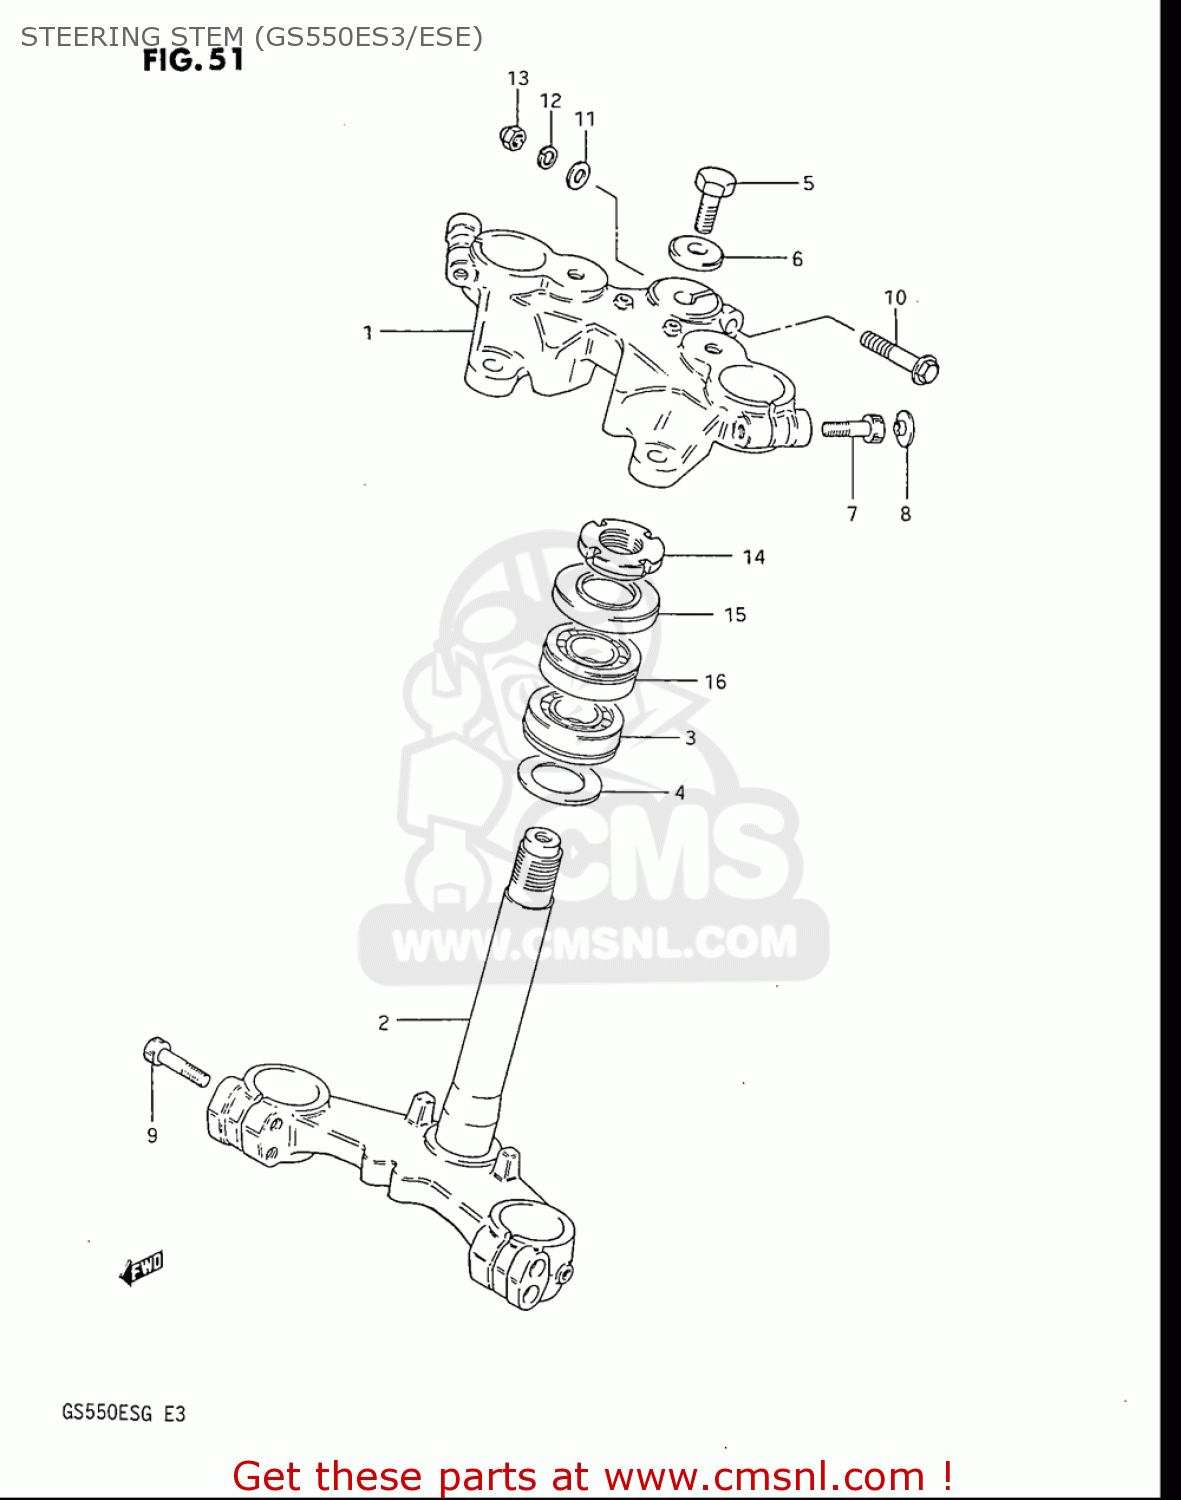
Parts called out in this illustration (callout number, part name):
3	BEARING(30X55X17)
4	SHIM(30X40X1.5)
5	BOLT,STEERING STEM HEAD
6	WASHER,STEERING STEM
7	BOLT,FORK INNER TUBE FITTING
8	CAP(OD:20)
9	BOLT
10	BOLT
11	WASHER
12	WASHER,LOCK
13	NUT
14	NUT,STEERING STEM
15	DUST SEAL,STEERING UPR
16	BEARING(25X47X15)
